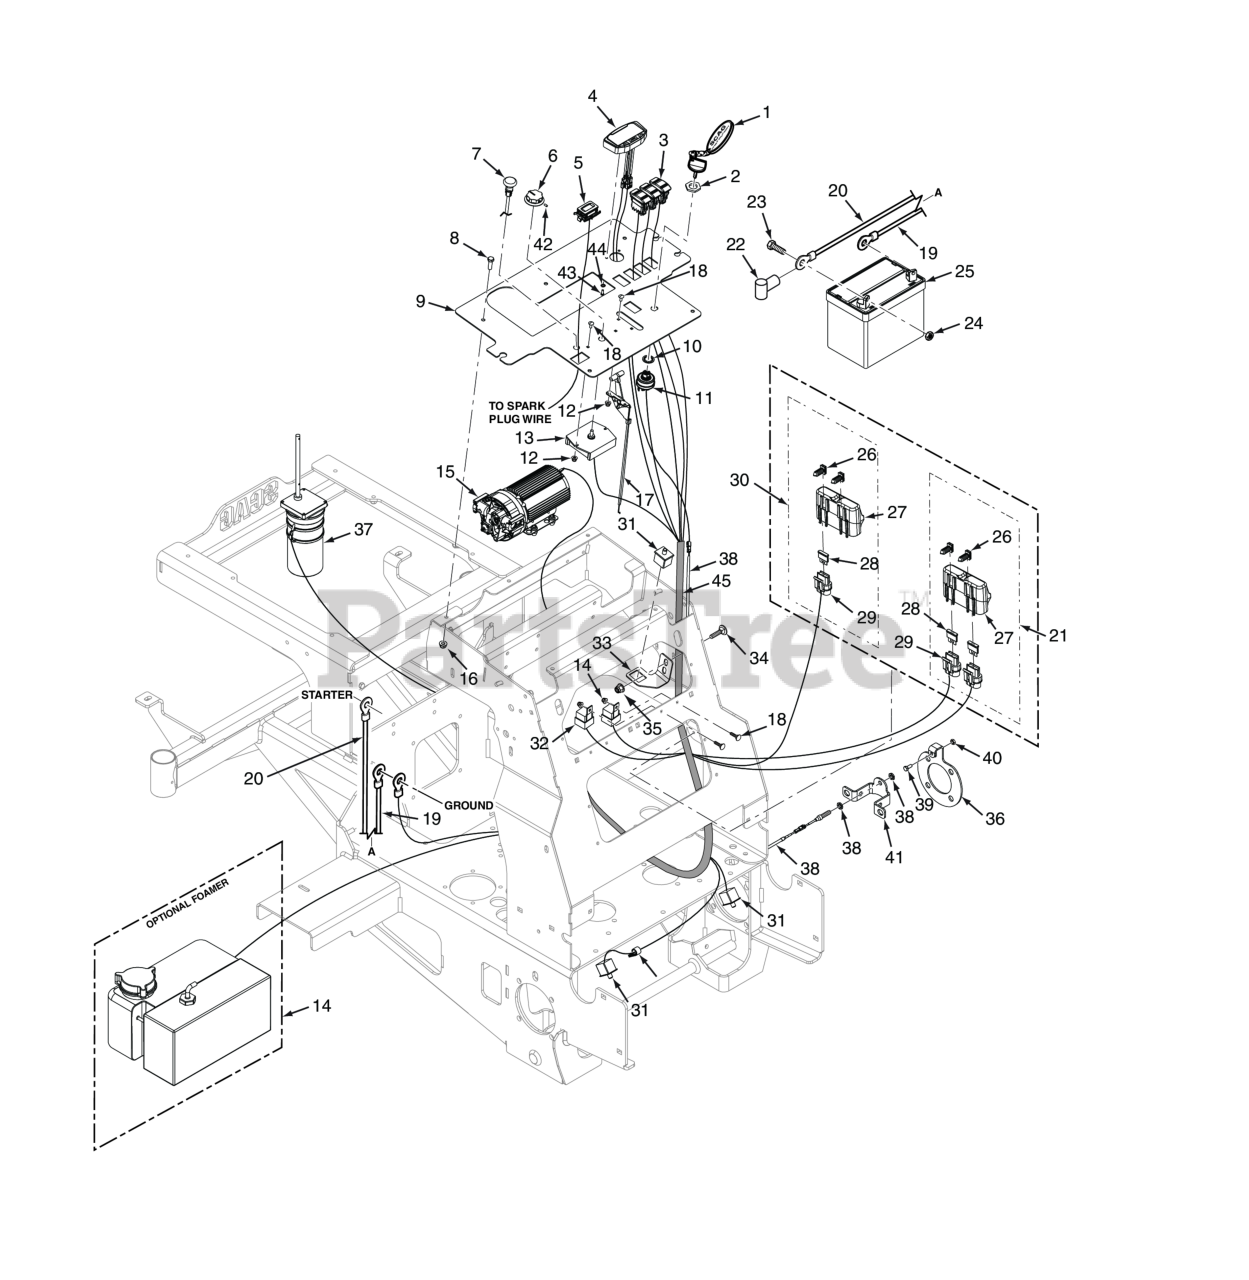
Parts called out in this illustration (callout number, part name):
1	Key, Assembly w/Fob
2	Nut, 5/8-32 Special
3	Switch, Rocker - Lighted
4	Display, Trail Tech
5	Hour Meter, Inductive
6	Knob (Incl #38)
7	Choke Control (excludes EFI models)
8	Bolt, Hex 5/16" - .375 x 1.00- Stainless Steel
9	Instrument Panel w/ Decal
10	LOCK WASHER, 5/8" INTERNAL TOOTH
11	KEY SWITCH(INCLUDES MOUNTING HARDWARE)
12	Locknut, #10 - 32 Elastic Stop - Stainless Steel
13	Motor Controller
14	Foamer Accessory (optional)
15	Pump, 12V Electric
16	Locknut, 5/16-18 Flg. Elastic Stop - Stainless Steel
17	Throttle Control, SVR
18	Bolt, Carriage #10 - 32 x .50 - Stainless Steel
19	Battery Cable, 31-1/2" Black (25KA, 26DFI, 31DFI) - Kawasaki
20	Battery Cable, Red
21	Double Fuse Assy.
22	RUBBER BOOT
23	BOLT, HEX HEAD, 1/4-20 X 3/4 GR.5
24	Nut, 1/4 - 20 Hex
25	Battery, 350 CCA (not available through Scag)
26	Clip, Fuse Holder
27	Cover, Sealed Double
28	FUSE, 20 AMP BLADE TYPE AUTOMOTIVE
29	Fuse Holder Assembly
30	Double Fuse Assy.
31	Switch, Double Pole - Plunger
32	Relay, 12V 40 AMP Standard
33	Mounting Bracket, Brake Switch
34	Bolt, Carriage 5/16 - 18 x 1" - - Stainless Steel
35	Locknut, 5/16-18 Flg. Elastic Stop - Stainless Steel
36	Plate, Hub Magnet Holder
37	Gear Motor, Electric
38	Wire Harness, Display
39	Bolt, Magnetic
40	Nut, M6 x 1.00
41	Plate, Speed Sensor
42	Set Screw, #8 - 32 x .375
43	Bolt, Hex Head M4-.7 x 10
44	Lockwasher, M4-1.1 x 7.6 x .8
45	Wire Harness, STS
